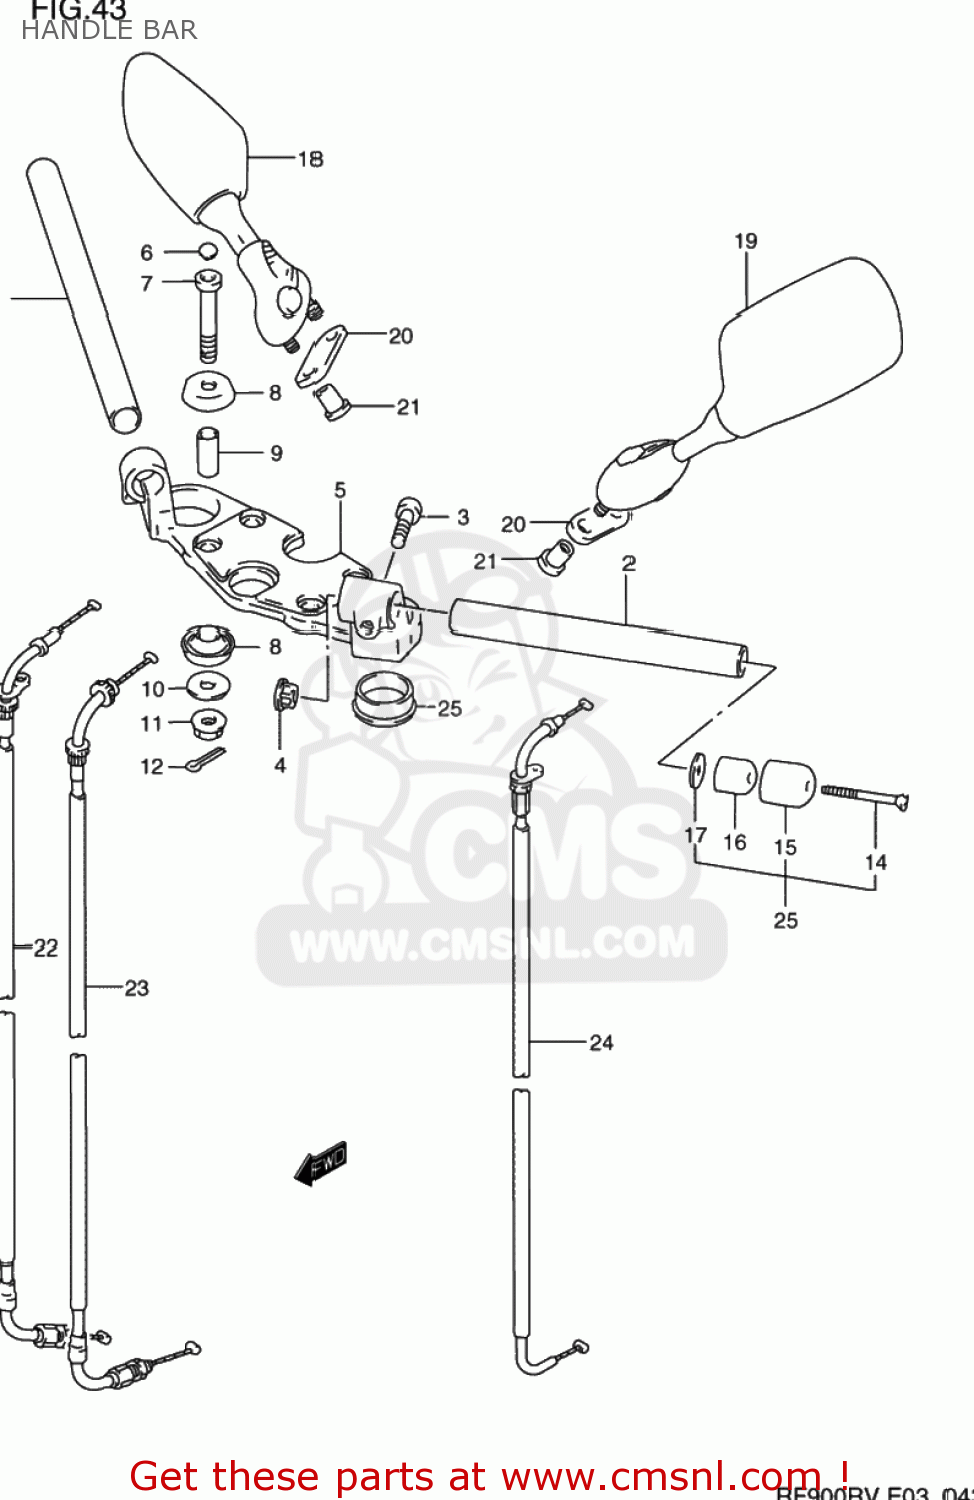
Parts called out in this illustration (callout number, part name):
1	HANDLEBAR
2	HANDLEBAR,L
3	BOLT
4	CAP,HANDLEBAR
5	HOLDER,HANDLEBAR
6	CAP(OD:11)
7	BOLT(10X66)
8	CUSHION,UPR BRACKET
9	SPACER
10	WASHER(10.5X30X3.2)
11	NUT
12	PIN 20X20
13	BALANCER SET,HANDLEBAR
14	SCREW
15	CAP,BALANCER
16	BALANCER,HANDLEBAR
17	SPACER,BALANCER
18	MIRROR ASSY,RR VIEW,R
19	MIRROR ASSY,RR VIEW,L
20	CUSHION,RR VIEW MIRRORR
21	NUT,RR VIEW MIRROR
22	CABLE ASSY,THROTTLE NO.1
23	CABLE ASSY,THROTTLE NO.2
24	CABLE COMP,STARTER
25	CUSHION,HANDLE HOLDER
